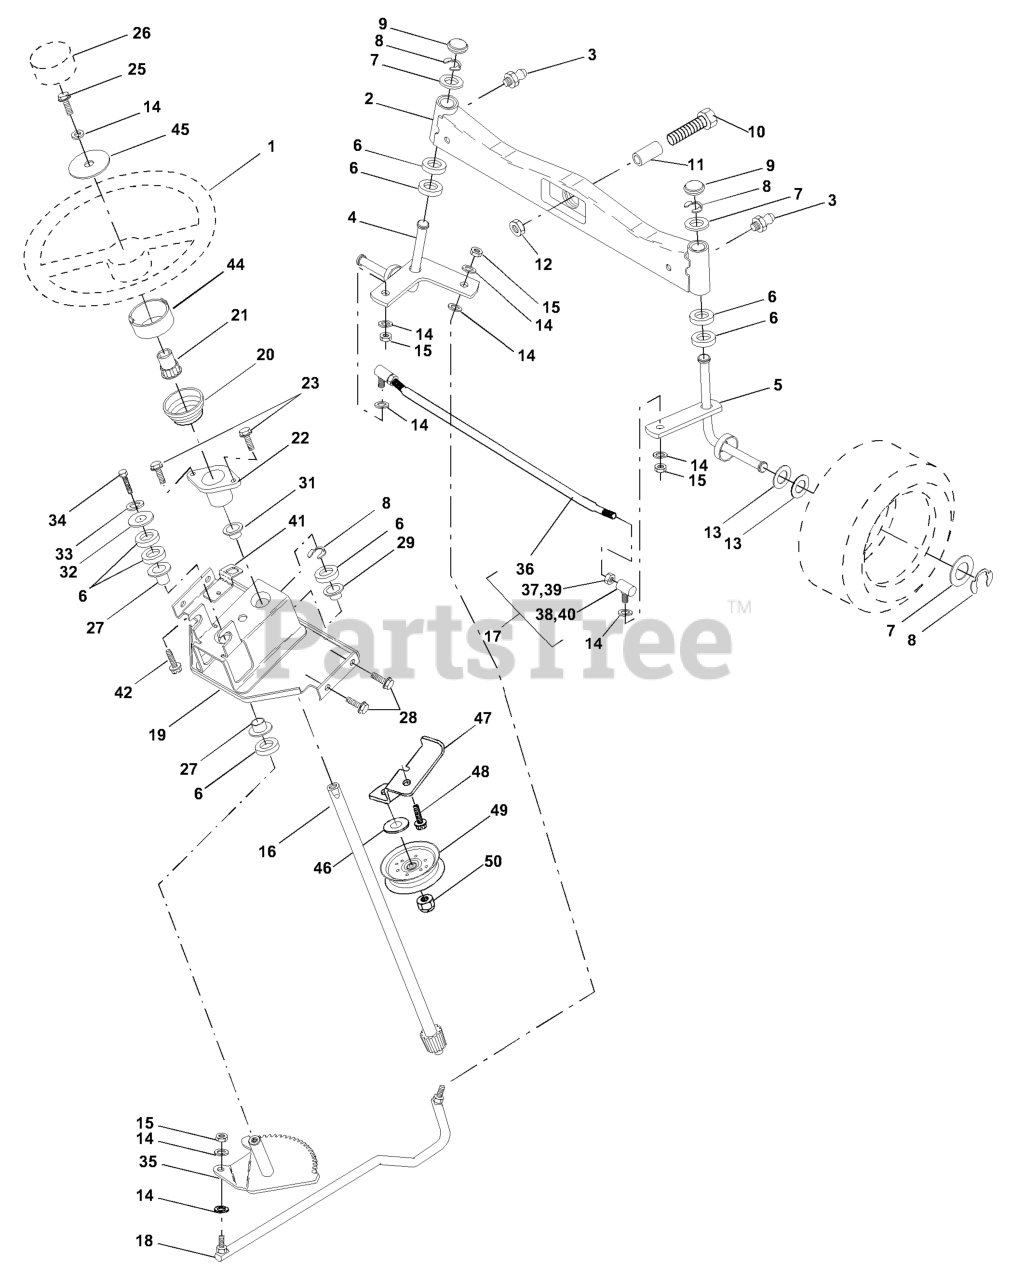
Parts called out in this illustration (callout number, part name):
1	Wheel, Steering
2	Axle Asm., Front
3	Fitting, Grease
4	Spindle Asm, LH
5	Spindle Asm., RH
6	Bearing, Race Thrust Harden
7	Washer 25/32 x 1-5/8 x 16 Ga.
8	Ring, Klip #T5304-75
9	Cap, Spindle
10	Bolt, Fin Hex 5/8-11 x 2-3/4
11	Spacer Brg Axle Front 1.570
12	Nut, Lock Flange 5/8-11 Unc
13	Washer 25/32 x 1-1/4 x 16 Ga.
14	Washer, Lock Hvy Hlcl Spr 3/8
15	Nut Lock Center 3/8-24 Unf
16	Shaft Asm., Steering
17	Rod Asm., Tie Ball J Ball Vgt
18	Draglink, Ball Joint Solid Vgt
19	Support Asm., Steering Vgt
20	Boot Steering
21	Adapter, Wheel Steering
22	Bushing, Strg.
25	Bolt, Fin Hex 3/8-16 x 1 Gr. 5
26	Cap , Wheel Steering
27	Bearing, Col. Strg.
28	Screw 3/8-16 x 3/4
29	Bearing, Flange
31	Bushing, Nyliner Snap
32	Washer 11/32 x 1 x 10 Ga.
33	Washer, Lock Hvy Hlcl Spr 5/16
34	Bolt, Hex Hd 5/16-18 x 3/4
35	Gear, Sector Steering
36	Tie Rod
37	Jam Nut RH Thread
38	Joint Asm. Ball RH Thread
39	Nut Hex Jam 3/8-24 UNF LH
40	Joint Asm Ball RH
41	Bracket Switch Inerlock VGT97
42	Screw 5/16-18 x 1/2
44	Extension Steering Premium
45	Washer 13/32 x 1-1/20 x 11 Ga.
46	Washer 13/32 x 7/8 x 10 Ga.
47	Bracket Asm. Idler
48	Screw 3/8-16 x .75
49	Pulley Idler Flat
50	Nut Lock Flg 3/8-16 Unc
